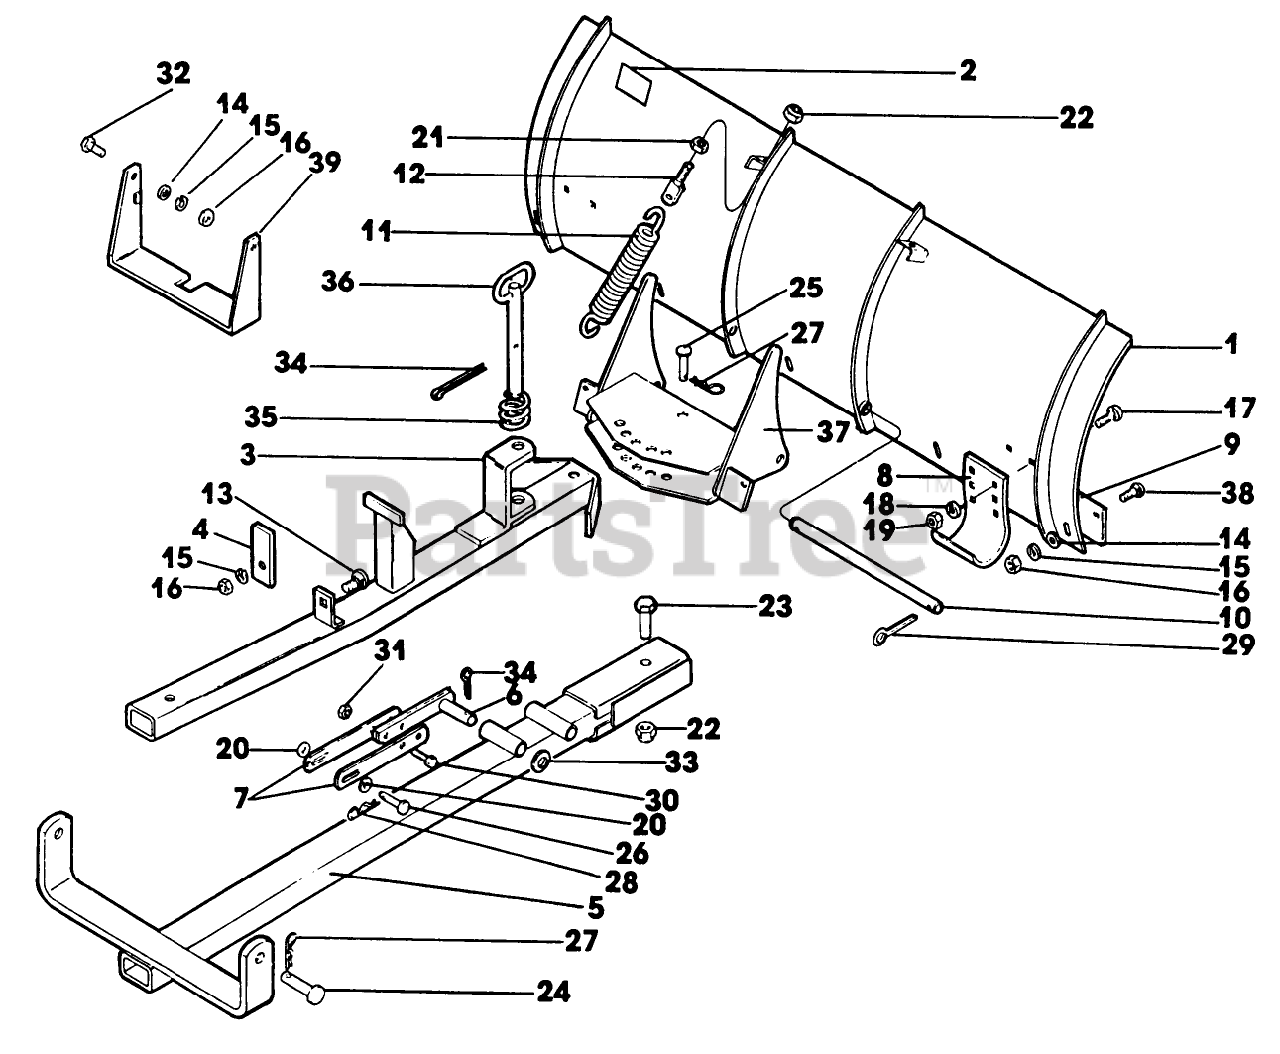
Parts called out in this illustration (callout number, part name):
9	BLADE SCRAPPER
16	NUT SS
18	WASHER
19	NUT
22	NUT-HEX CONE LOK
25	PIN-CLEVIS
28	PIN - SPRING CLIP
31	NUT-HEX
32	SCREW
39	STABILIZER
